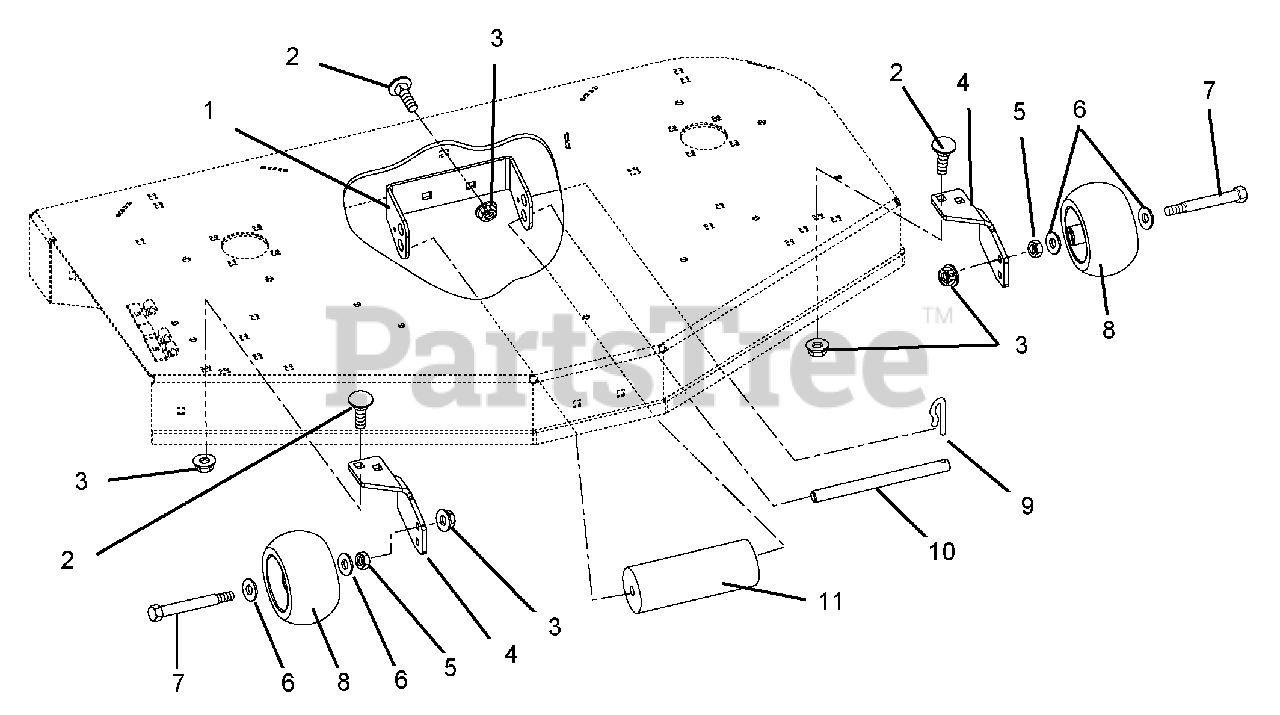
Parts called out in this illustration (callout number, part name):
1	BRACKET, ROLLER MOUNT
2	BLT-RDHDSQNK .38-16X1.00 G5YZ
3	@NUT-LK-NYL-FLG .38-16 YWZC
4	BRACKET, ANTI SCALP
5	@NUT-LK-CTR-JAM .375-16 YWZC
6	@WSHR-FL-STL.406X.812X.065 YWZ
7	@BLT-HEX .38-16X3.50 GR5 YWZC
9	PIN, SPRING CLIP
10	PIN, ROLLER
